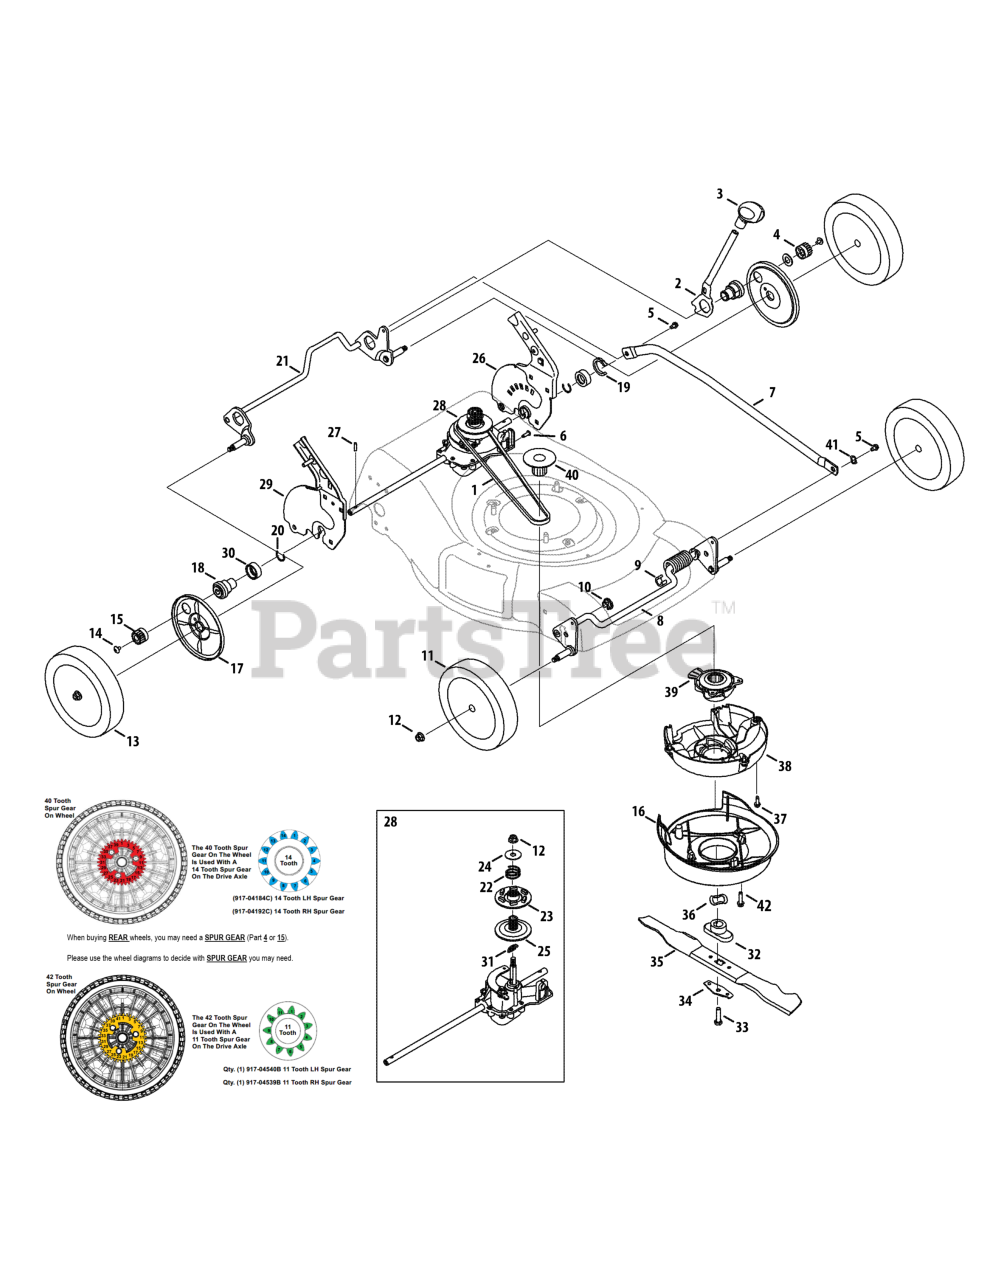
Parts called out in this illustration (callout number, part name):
1	V-Belt
2	Spring Lever
4	Spur Gear, 14T - LH
5	Shldr. Screw, 1/4-20 x 0.50
6	Screw, #12-16 x .750
9	Clip Spacer
10	Split Hex Flange Bearing
11	Front Wheel
12	Flange Lock Nut, 3/8-16
13	Rear Wheel
14	Screw, 1/4-20 x .39
15	Spur Gear, 14T - RH
17	Wheel Dust Cover
18	Transmission Bearing Support
19	Clip Spacer
20	Retaining Ring .875
22	Compression Spring
23	Upper Pulley
24	Flat Washer, .442 x 1.38 x .060
25	Lower Pulley
27	Dowel Pin
28	Transmission Assembly
30	Bearing Support Spacer
31	Extension Spring
32	Blade Adapter
33	Screw, 3/8-24 x 1.50
34	Blade Bell Support
35	21" Mulching Blade
36	Washer, Wave, 1.5 x 1.0 x .029
37	TT Screw, 1/4-20 x .500
38	Engine Baffle
39	Lower Pulley Assembly
40	Pulley, Half
41	Washer, Wave, .390 x .625 x .016
42	Screw, 1/4-15 x 1.00
